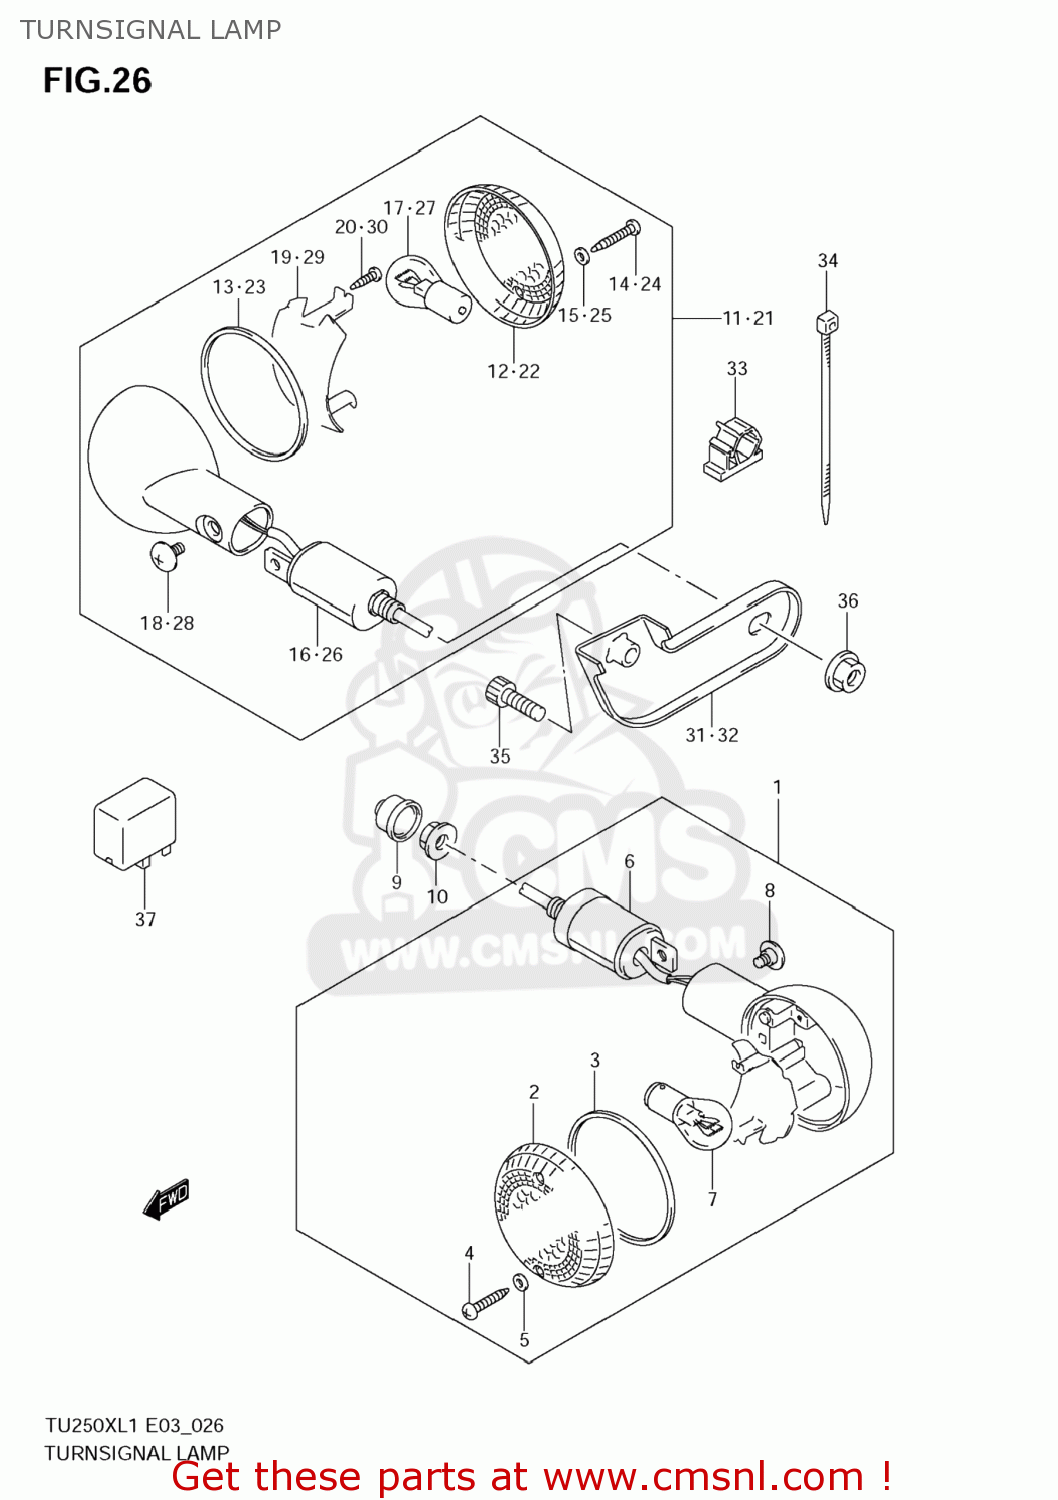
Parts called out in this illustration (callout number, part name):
1	LAMP ASSY,FR TURN SIGNAL
2	LENS
3	GASKET (NAS)
4	SCREW
5	GASKET (NAS)
6	STAY,TURNSIGNAL FR
7	BULB(12V21W)
8	SCREW
9	COVER,TURNSIGNAL
10	NUT
11	LAMP ASSY,RR TURNSIGNAL,R
12	LENS
13	GASKET (NAS)
14	SCREW
15	GASKET (NAS)
16	STAY,TURNSIGNAL FR
17	BULB(12V21W)
18	SCREW
19	REFLECTOR
20	SCREW
21	LAMP ASSY,RR TURNSIGNAL,L
22	LENS
23	GASKET (NAS)
24	SCREW
25	GASKET (NAS)
26	STAY,TURNSIGNAL FR
27	BULB(12V21W)
28	SCREW
29	REFLECTOR
30	SCREW
31	BRACKET,RR TURNSIGNAL,R
32	BRACKET,RR TURNSIGNAL,L
33	CLAMP
34	CLAMP(L:145)
35	BOLT
36	NUT
37	RELAY ASSY,TURNSIGNAL LAMP
